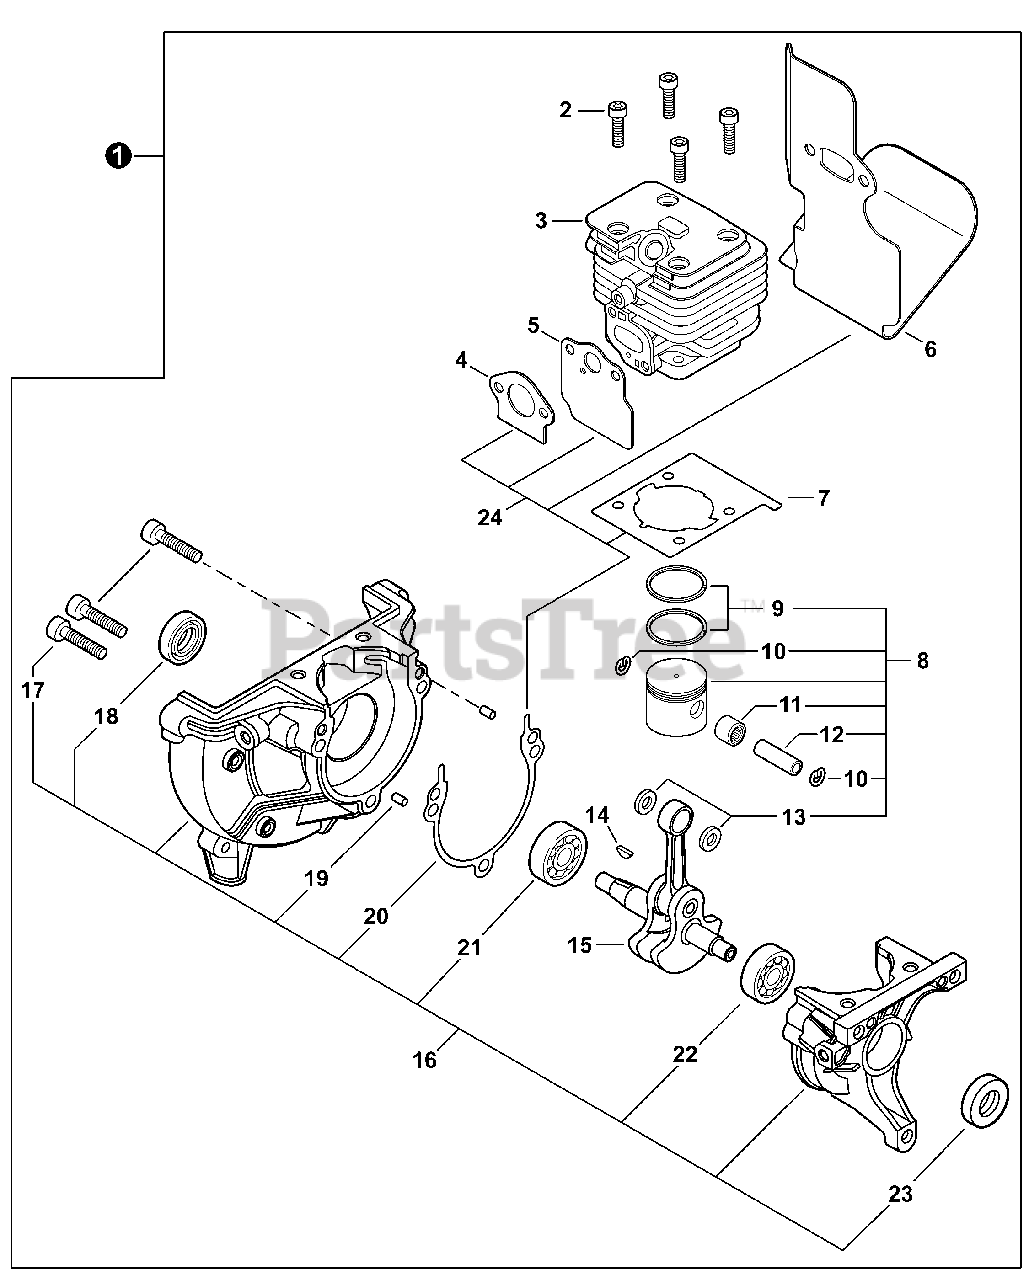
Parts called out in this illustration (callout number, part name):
1	SHORT BLOCK
2	BOLT, TORX 5×20
3	CYLINDER
4	GASKET, INTAKE
5	HEAT SHIELD, INTAKE
6	HEAT SHIELD, EXHAUST
7	GASKET, CYLINDER
8	PISTON KIT
9	RING, PISTON
10	RING, SNAP
11	BEARING, NEEDLE 9
12	PIN, PISTON
13	WASHER, THRUST
14	KEY, WOODRUFF
15	CRANKSHAFT ASSY
16	CRANKCASE KIT
17	BOLT, TORX 5×25
18	SEAL, OIL 12
19	PIN, LOCATING 4×8
20	GASKET, CRANKCASE
21	BEARING, BALL 6001
22	BEARING, BALL
23	SEAL, OIL 10
24	GASKET KIT
